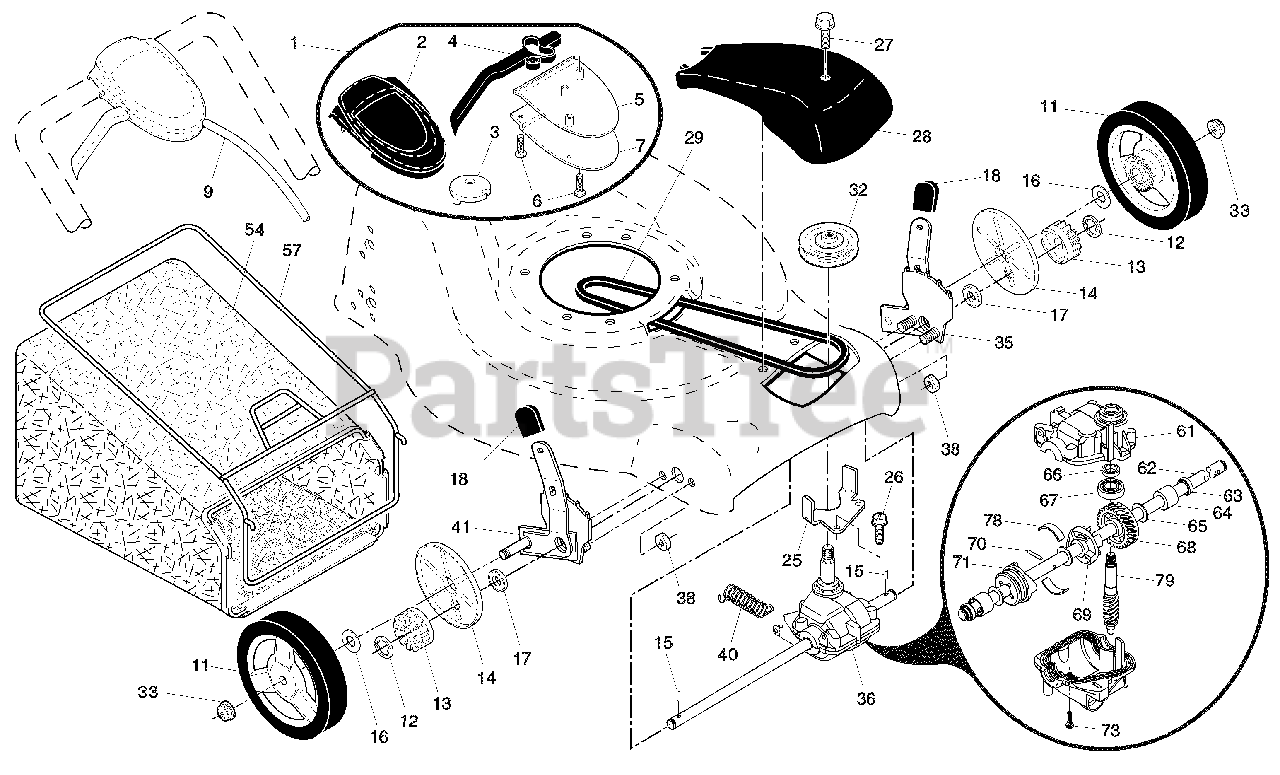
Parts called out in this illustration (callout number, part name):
1	Drive Control Assembly
2	Cover, Drive Control, Upper
3	Pulley
4	Lever, Drive Control
5	Cover, Drive Control, Lower
7	Bracket, Drive
9	Cable Assembly, Drive
11	Wheel & Tire Assembly
14	Dust Cover
15	Pawl, Drive
16	Washer 1/2 x 1-1/2 x .134
17	Bearing, Wheel Adjuster
18	Selector Knob
25	Belt Keeper
26	Screw, Hi-Lo Thread
27	Pan Head Tapping Screw #10-24 x 2-3/4
28	Drive Cover
32	Drive Pulley
33	Locknut, Hex
35	Kit, Wheel Adjuster, LH
36	Gearcase Assembly, Complete
38	Locknut, Hex 1/4-20
41	Kit, Wheel Adjuster, RH
54	Grassbag Assembly
57	Frame, Grassbag
61	Case, Upper
62	Shaft, Output
63	Seal, Output Shaft
66	Seal, Worm Shaft
67	Bearing, Ball
68	Gear, 28 Teeth
69	Fixed Dog Clutch
70	Pin
71	Movable Dog Clutch
73	Screw, Case
74	Case, Lower
78	Spring, Leaf
79	Shaft, Worm
